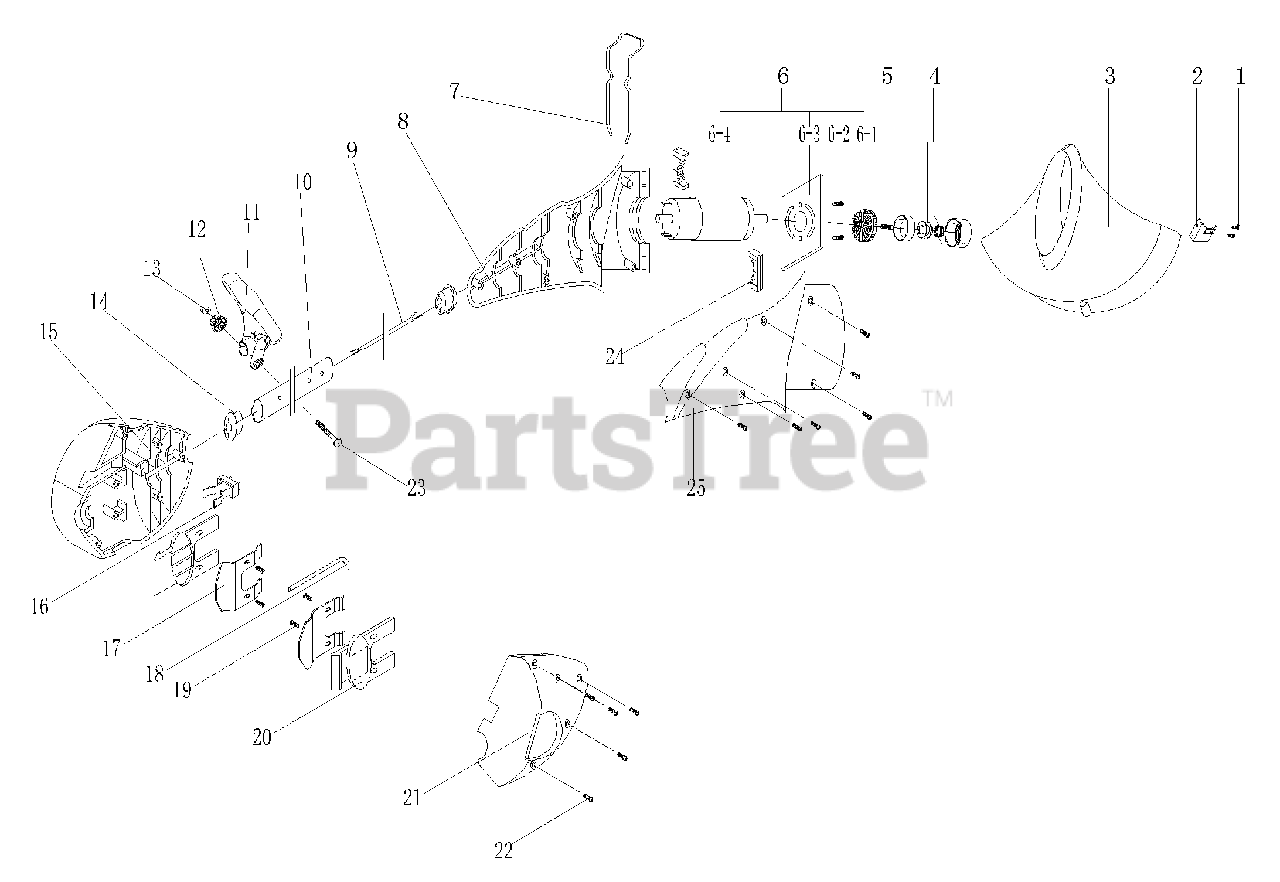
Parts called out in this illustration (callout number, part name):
4	SPOOL ASS'Y
6	MOTOR ASS'Y
8	HOUSING (L)
15	CONNECT (L)
16	TERMINAL ASS'Y
17	SPRING LAMINATION
21	CONNECT (R)
25	HOUSING (R)
